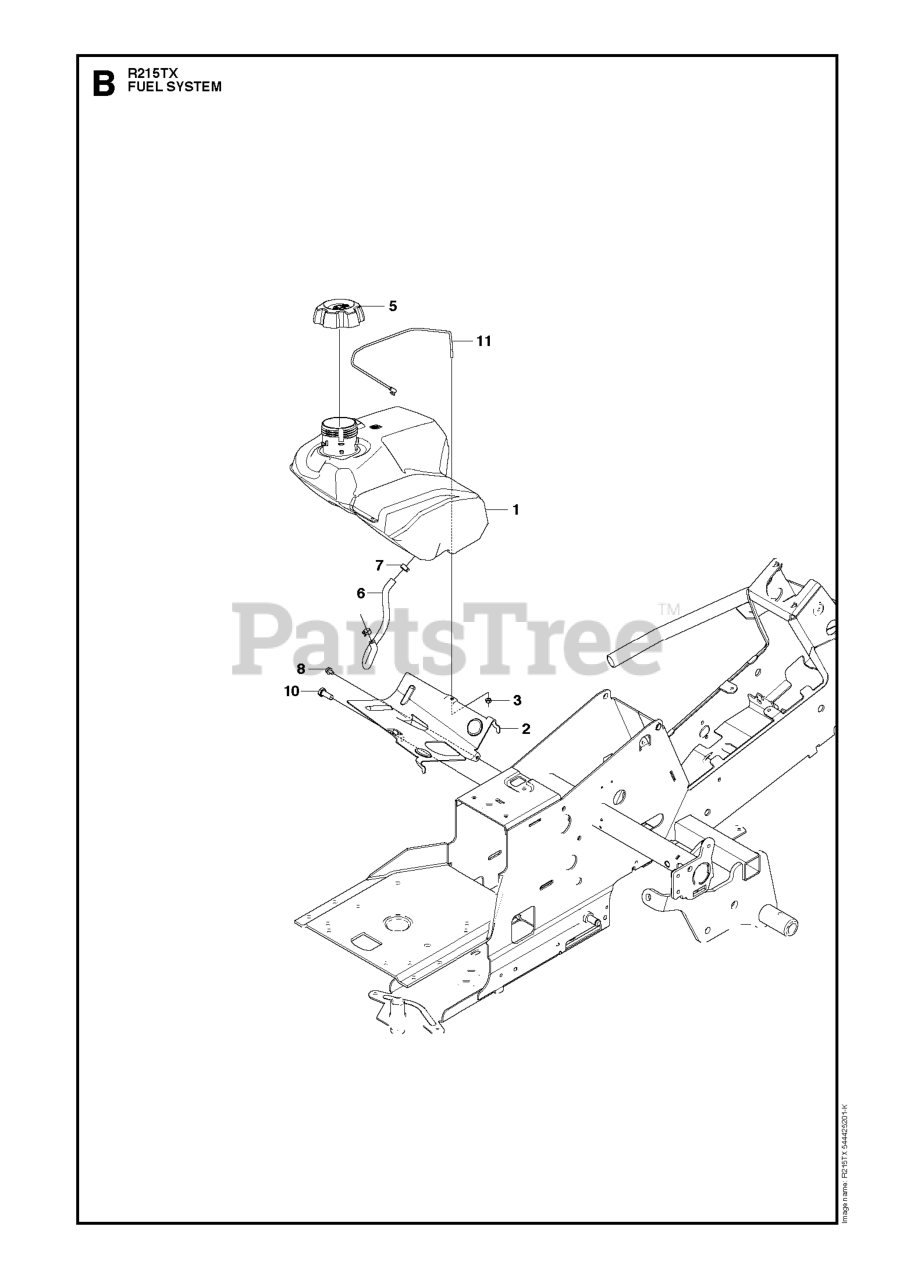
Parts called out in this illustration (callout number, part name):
3	LOCKNUT M6
5	CAP.FL.R.3'N/CARB.H.CROWN.498
10	Screw M10x25
